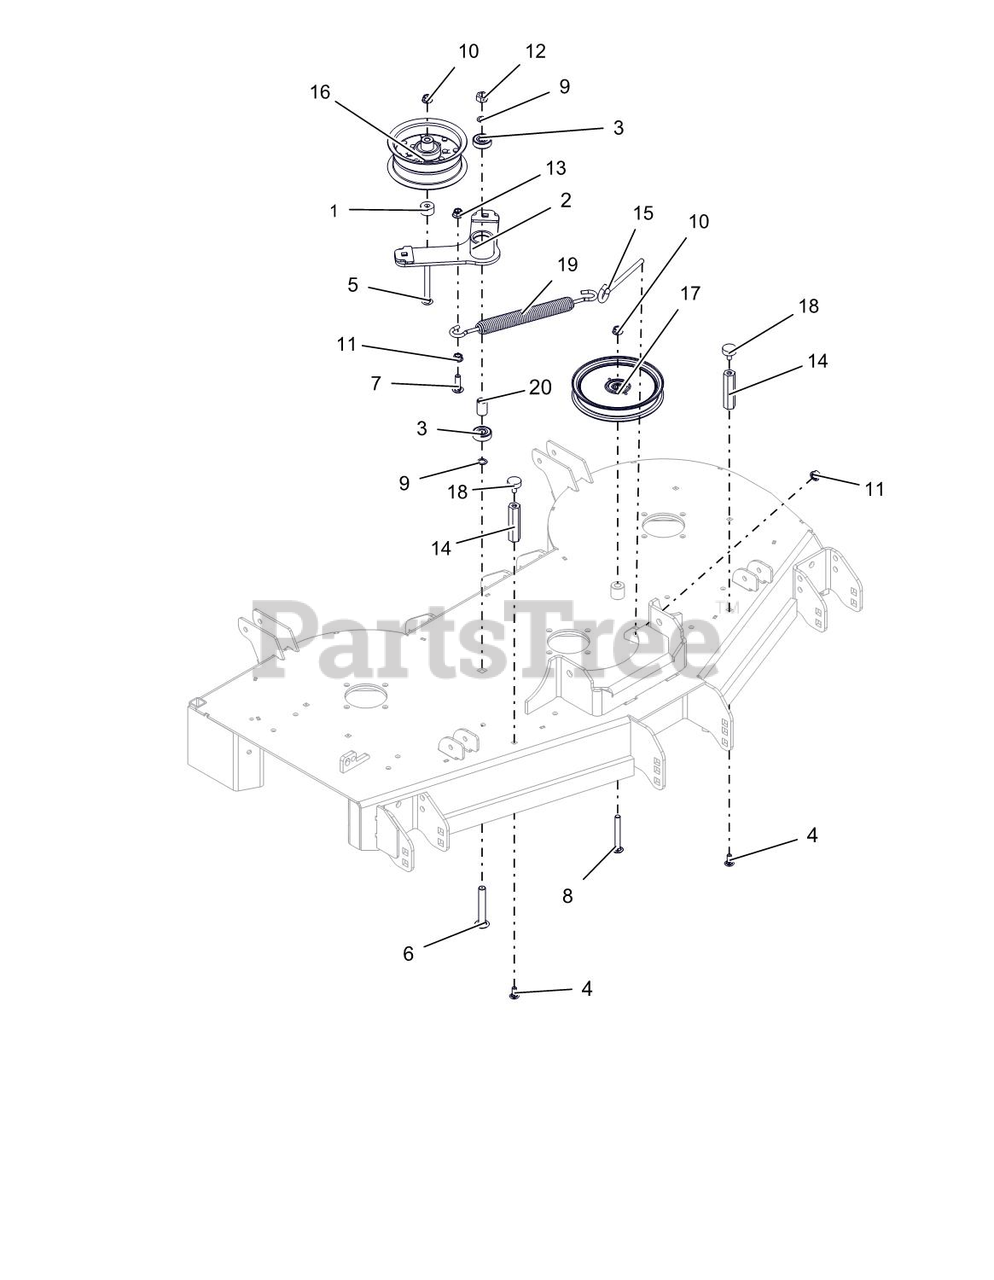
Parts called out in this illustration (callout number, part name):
1	SPACER .390X1.000X.562
2	WLDMT, DECK IDLER ARM
3	BRG-BALL .500X1.38X.437
4	BLT,RDHDSQNK .31-18X.75 LOCTIT
5	BLT-RHDSSQNK .38-16X3.50 G5YZ
6	BLT,RDHDSQSHNK.50-13X3.25 G5YZ
7	BLT-RHDSSQNK .38-16X1.25 G5YZ
8	BLT-RDHDSQNK .38-16X3.00 G5YZ
9	WASHER, .500X.750X.020 THRUST
10	NUT-LK-CTR-FLG .38-16 YWZC
11	NUT-SPNLK-FLG .375-16 YWZC
12	NUT-LK-CTR .50-13 YWZC
13	NUT-LK-NYL-FLG .38-16 YWZC
14	NUT, COUPLING .31-18 X 3.00
15	BOLT,.38-16 X 4.25-.62 DIA EYE
16	PULLEY, FLAT 5.00X2.36X.375
17	IDLER, FLAT-6.00" X .75"
18	BUMPER, RUBBER
19	SPRING, EXTENSION
20	SPACER .510 X .75 X 1.1485
